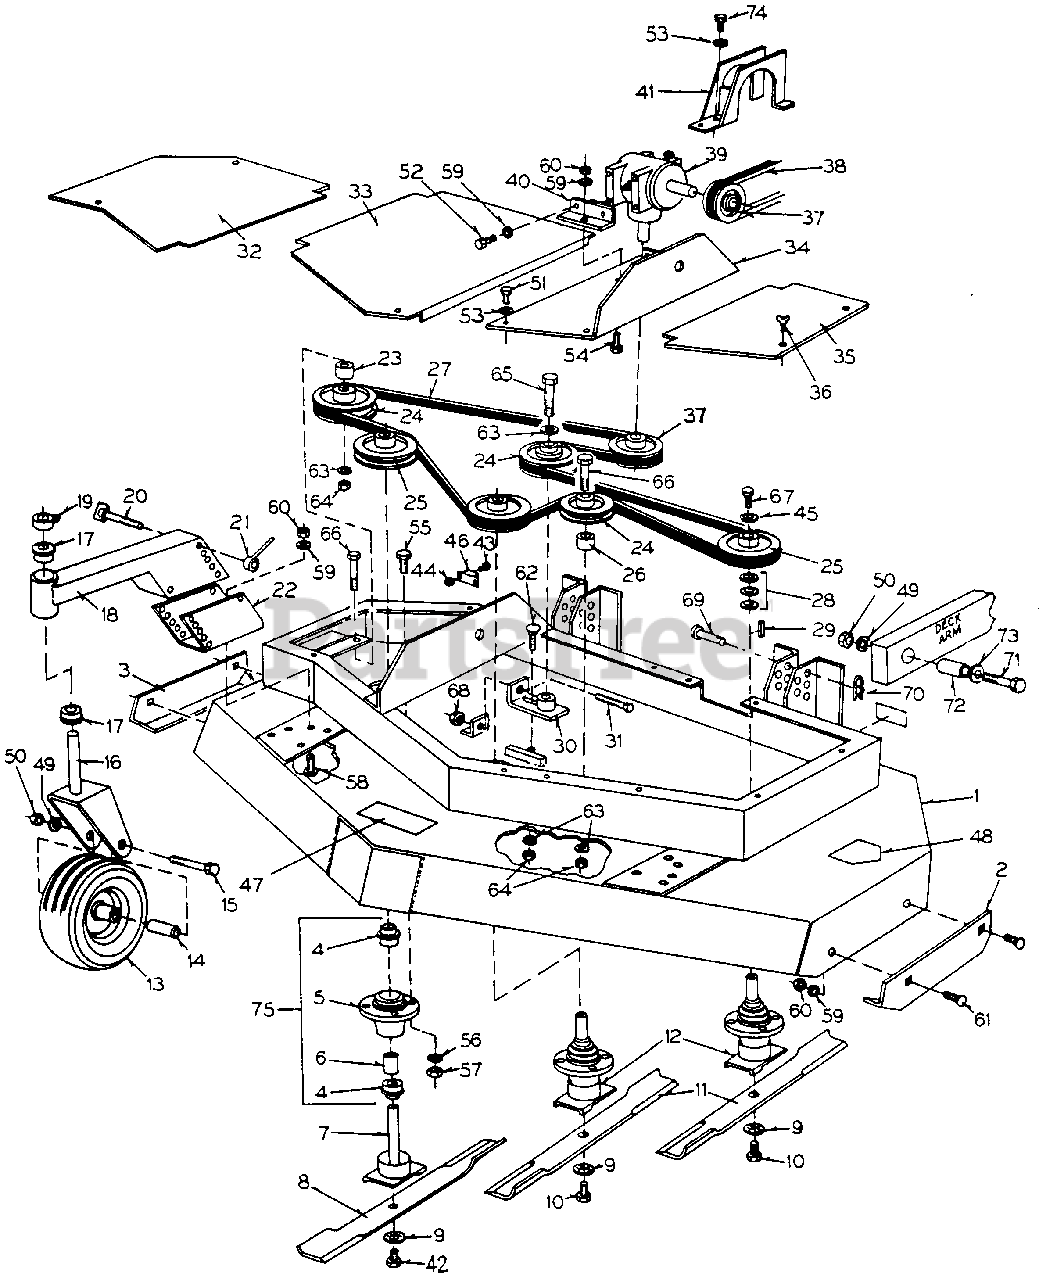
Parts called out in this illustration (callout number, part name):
1	Rear Discharge Deck, 52"
4	Spindle Bearing
5	Spindle Housing
7	Spindle Shaft, LH
10	Hex Bolt, 3/8-24 x 1 1/4, GRS
12	Spindle Shaft, RH
13	Gauge Wheel Assembly
14	Axle
15	Hex Bolt, 1/2-13 x 6 1/2, GR2
18	GaugeWheel Mount
22	GaugeWheel Mount Bracket
23	IdlerSpacer, RH
25	Spindle Pulley
26	Idler Pulley Spacer
29	Key, 3/16 x 3/16 x 1"
30	Belt Tightener
31	Hex Tap Bolt, 1/4-20 x 4 "
36	ThumbScrew, 1/4-20x 1/2
37	Gearbox Pulley
38	Deck Drive Belt
39	Gearbox Assembly
40	Gearbox Mount Angle
42	Hex Bolt, 318-24 x 1 1/4, GRS, LH
43	Panhead Machine Screw, No. 10- 32x1/2 *
44	Integral Star Washer Nut, No. 10-32
45	Spindle Washer
46	10 Amp Circuit Breaker
47	Decal, Caution-Whirling Blade
49	Lockwasher, 1/2" *
50	Hex Nut, 1/2-13 *
51	Hex Capscrew, 114-20 x 3/4, GR5 *
52	Hex Capscrew, 5/16-18 x l, GR5 *
53	Lockwasher, 1/4 *
55	Hex Capscrew, 7/16-14 x 1 1/4, GRS *
56	Lockwasher, 7/16 *
58	Carriage Bolt, 5/16-18 x 1, GRS *
59	Lockwasher, 5/16 *
60	Hex Nut, 5/16 *
61	Carriage Bolt, 5/16-18 x 3/4 *
62	Carriage Bolt, 3/8-16x l *
63	Lockwasher, 3/8 *
67	Hex Capscrew, 5/16-24 x 3/4, GRS
68	Elastic Stop Nut, 1/4-20 *
69	Clevis Pin, 1/2x 1 1/2
70	Hairpin Cotter, .120 x 21/4
71	Hex Capscrew, 1/2-13 x l 1/2 GR5 *
72	Bushing, Deck Lift Arm
73	Flatwasher, 1/2 *
74	Hex Capscrew, 1/4-20 x 1/2, GR5 *
75	Spindle Housing Assembly
